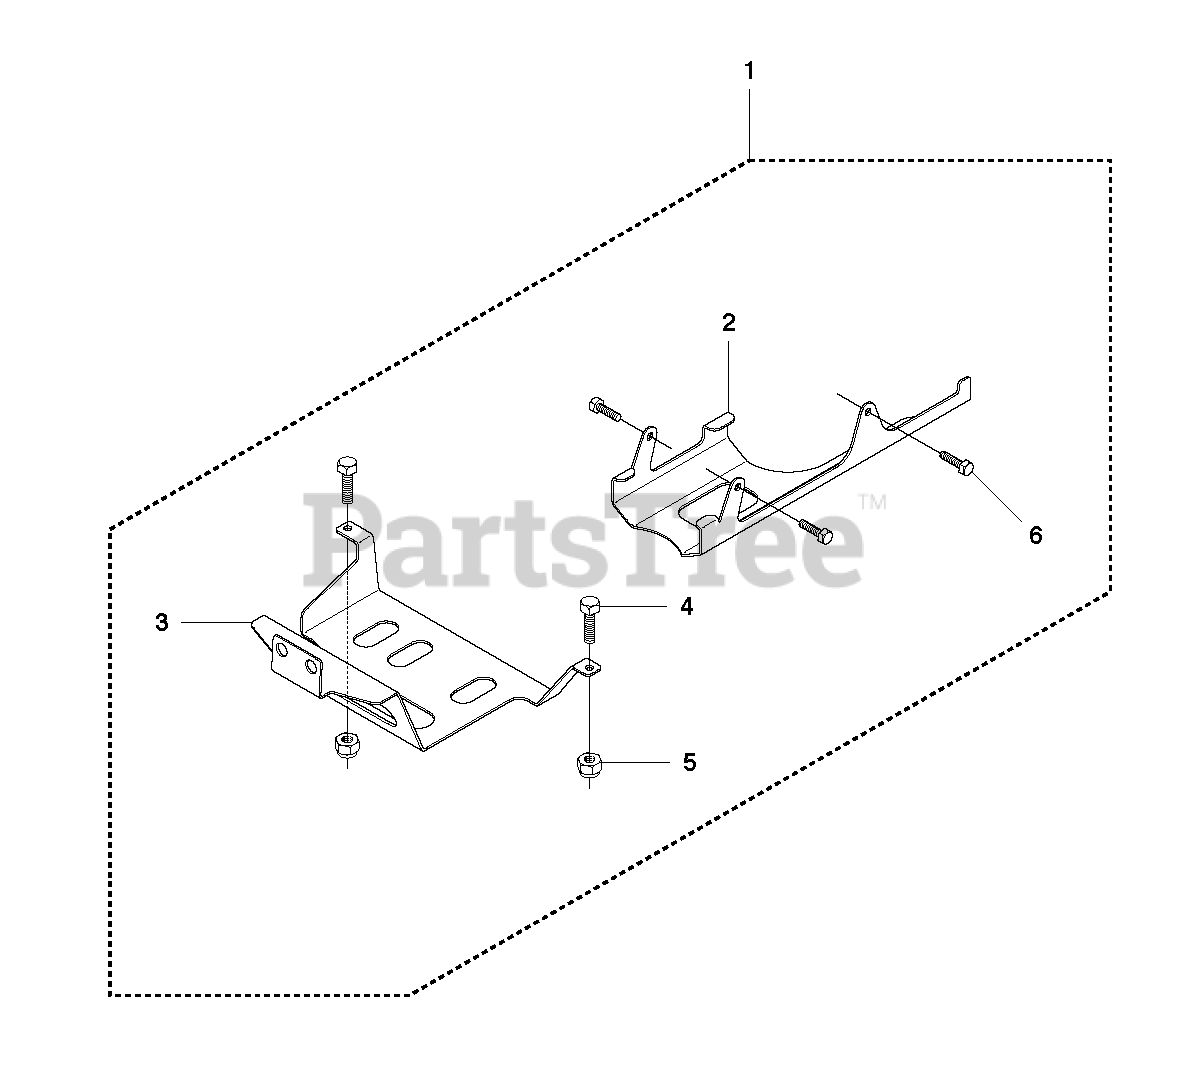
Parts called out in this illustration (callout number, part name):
2	KIT
3	RP PROTECTION PLATE REAR
4	SCREW
5	LOCKNUT M8
6	BOLT FLANGE - M8X16
